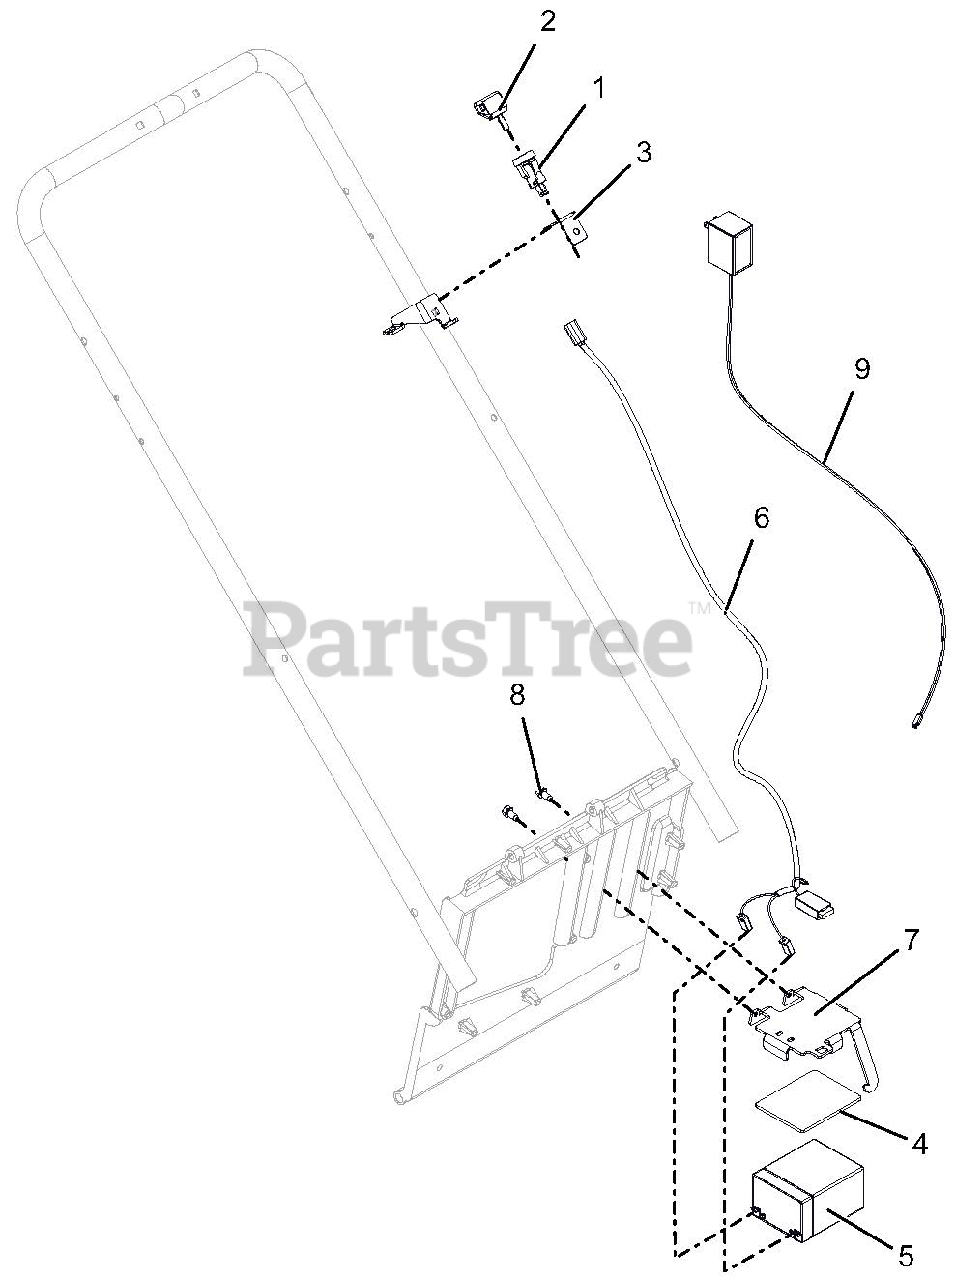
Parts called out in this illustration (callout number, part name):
1	SWITCH, KEY
2	KEYS, IGNITION
3	BRKT, KEY SWITCH
4	PAD, BATTERY, LM
5	BATTERY, AGM, 2.9AH, GNRL PRPS
6	HARNESS, ELEC START
7	BRKT, BATTERY HOLD DOWN
8	SCR-TAP .25-20X.50 HWH TR YWZ
9	CHARGER, BATTERY
